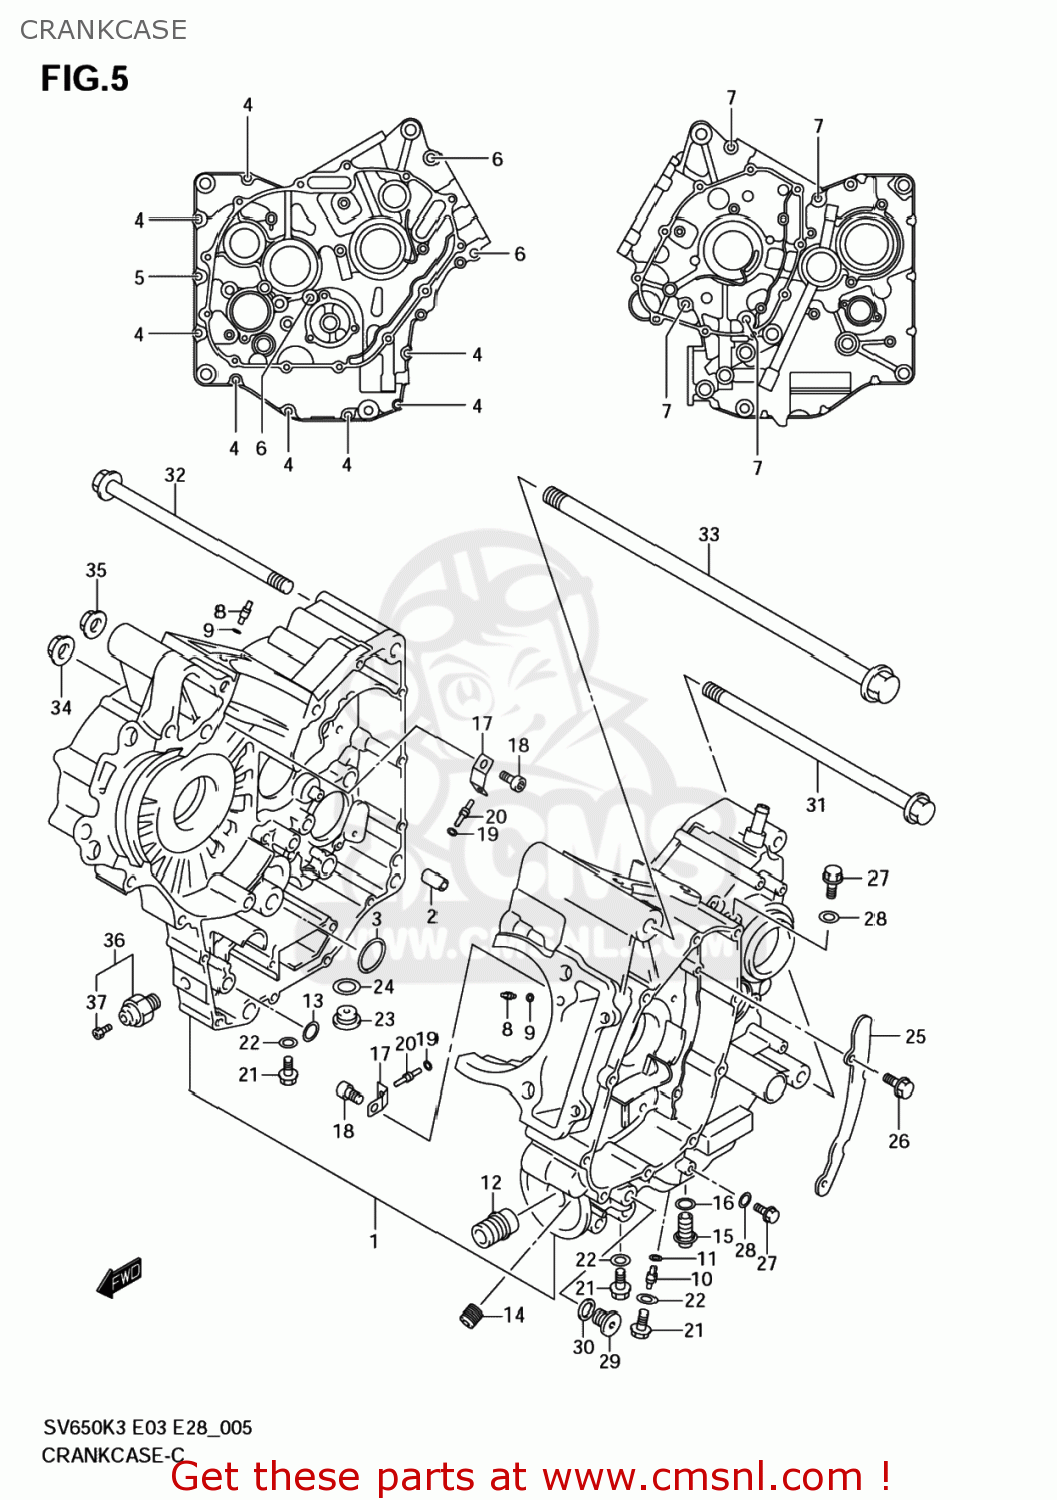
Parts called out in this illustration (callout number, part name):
1	CRANKCASE SET
2	PIN(8.4X11X20)
3	O RING(D:2.4,ID:15.8)
4	BOLT
5	BOLT
6	BOLT
7	BOLT
8	JET,AIR(14)
9	O RING(D:1.2,ID:4)
10	JET,AIR(14)
11	O RING(D:1.2,ID:4)
12	UNION,OIL STAND
13	O RING(D:1.9,ID:12.6)
14	JET,OIL GALLERY(3.6)
15	PLUG(12X20)
16	GASKET(12.1X16.2X3.7) (NAS)
17	PLATE,PISTON COOLING JET
18	BOLT(6X12)
19	O RING(D:1.2,ID:4)
20	JET(13)
21	BOLT
22	GASKET(8.2X14X1) (NAS)
23	PLUG,16X8
24	GASKET(16X22X2) (NAS)
25	PLATE,OIL SEPARATOR
26	BOLT
27	BOLT
28	GASKET(5.8X13X1.2) (NAS)
29	PLUG(L:12)
30	GASKET(12X17X1) (NAS)
31	BOLT(10X255)
32	BOLT(10X225)
33	BOLT(12X310)
34	NUT
35	NUT
36	SWITCH ASSY,OIL PRESSURE
37	BOLT,OIL PRESSURE SWITCH
